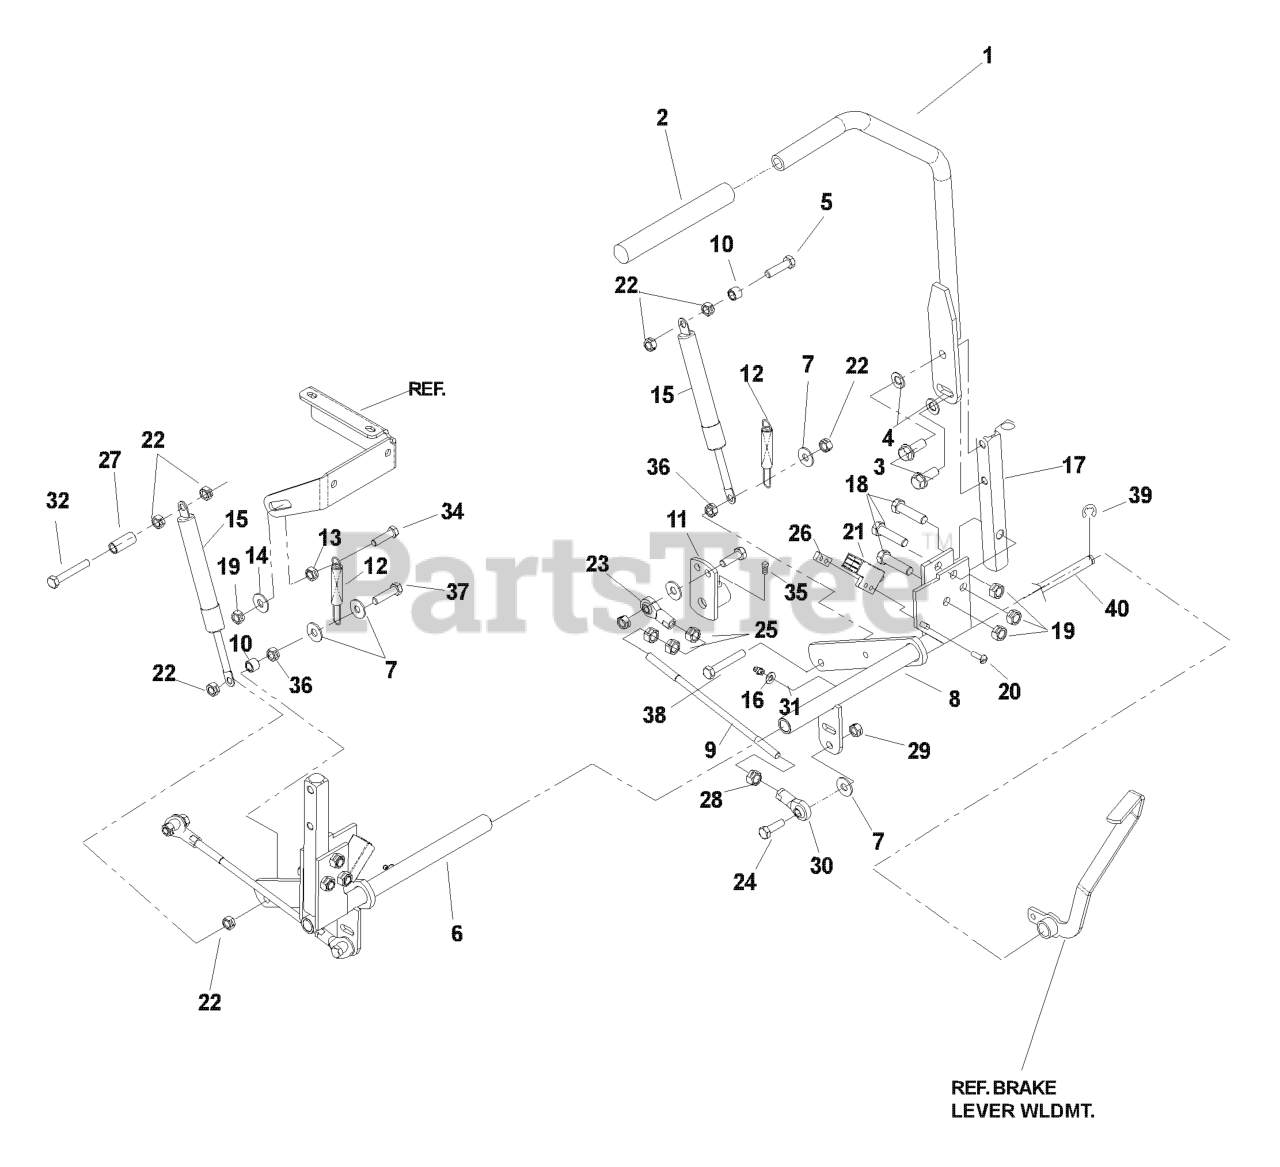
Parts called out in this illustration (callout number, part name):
1	CONTROL LEVER WELDMENT
3	HCS 3/8-16X1.GRD.5.ZD
4	WASHER, 3/8 DISC SPRING SPEC
5	CAPSCREW 5/16 X 1/1/2 HEX HEAD
6	CONTROL WLDMNT RH
7	WASHER 5/16 FLAT
8	CONTROL WLDMNT - LH
9	PUMP CONTROL LINK
11	PUMP LEVER
13	NUT 3/8C WHIZ
14	WASHER 3/8 FLAT
16	ZERK
17	CONTROL ARM
18	HCS 3/8-16 X 1 3/4 GR5
19	NUT 3/8-16 NYLOC
20	SCREW #10-24 X 5/8
21	SWITCH, INTERLOCK
22	NUT 5/16C CENTERLOCK
23	BALL JOINT, RIGHT HANDED
24	HCS 5/16C X 1 1/4
26	TAPPED PLATE
28	NUT 5/16F LEFTHAND
29	NUT 5/16 NYLOC
30	BALL JOINT, LEFT HANDED
32	HCS 5/16-18X2
33	HCS 3/8C X 3
34	HCS 3/8C X 2 1/2
35	5/16C X 5/8 "V" POINT
36	NUT 5/16C WHIZ
37	TAP BOLT 5/16C X 2 1/4
38	BOLT, TAP 5/16-18
39	E-RING 1/2 (2 2)
40	CONTROL SHAFT
